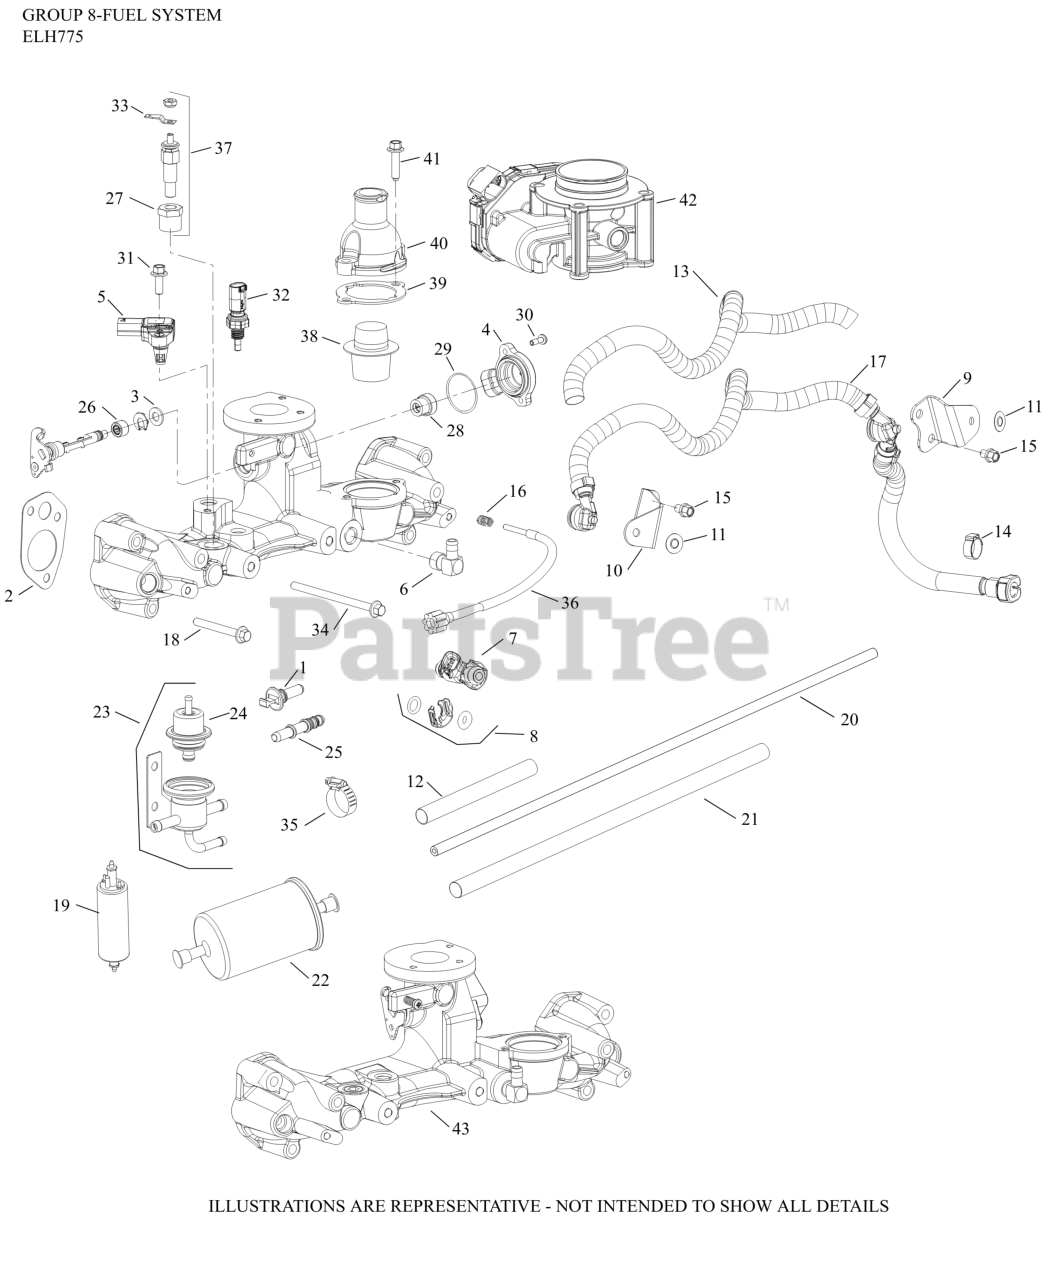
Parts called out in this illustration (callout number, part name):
1	PLUG, FITTING FUEL
2	GASKET, INTAKE MANIFOLD
3	SEAL, THROTTLE SHAFT
4	SENSOR, THROTTLE POSITION
5	SENSOR, T-MAP
6	CONNECTOR
6	CONNECTOR, HOSE
7	INJECTOR, FUEL
8	KIT, FUEL INJECTOR O-RING
9	BRACKET, INJECTOR CYLINDER #1
10	BRACKET, INJECTOR CYLINDER #2
11	CLIP, RETAINER
12	SLEEVE, ANTI ABRASION -USE 25 431 12-S
13	SLEEVE, ANTI ABRASION
14	CLAMP, HOSE
15	SCREW, M6 X 8 HEX FLANGE HEAD
16	SPRING, IDLE SET SCREW
17	RAIL ASSEMBLY, FUEL
18	SCREW, FLG M6X1.0X50
19	PUMP,FUEL ASSEMBLY(ELECTRIC)
21	SLEEVE, INSULATING 14"
22	FILTER, FUEL
23	REGULATOR ASSY, FUEL PRESSURE
24	REGULATOR, FUEL PRESSURE
25	FITTING, FUEL (STRAIGHT)
26	BEARING, NEEDLE
27	BUSHING, REDUCING
28	MAGNET, TPS SENSOR
29	O-RING, TPS SENSOR
31	SCREW, FLG M6X1.0X16
32	SENSOR, TEMPERATURE
33	TERMINAL, EYELET/SPADE
34	SCREW, FLG M6X1.0X90
35	CLAMP, HOSE (KM)-USE 25 237 31-S
36	CABLE, IDLE ADJUSTMENT
37	SENSOR ASSY, TEMPERATURE
38	KIT, THERMOSTAT (190 F degree)
39	GASKET, THERMOSTAT
40	HOUSING, THERMOSTAT
